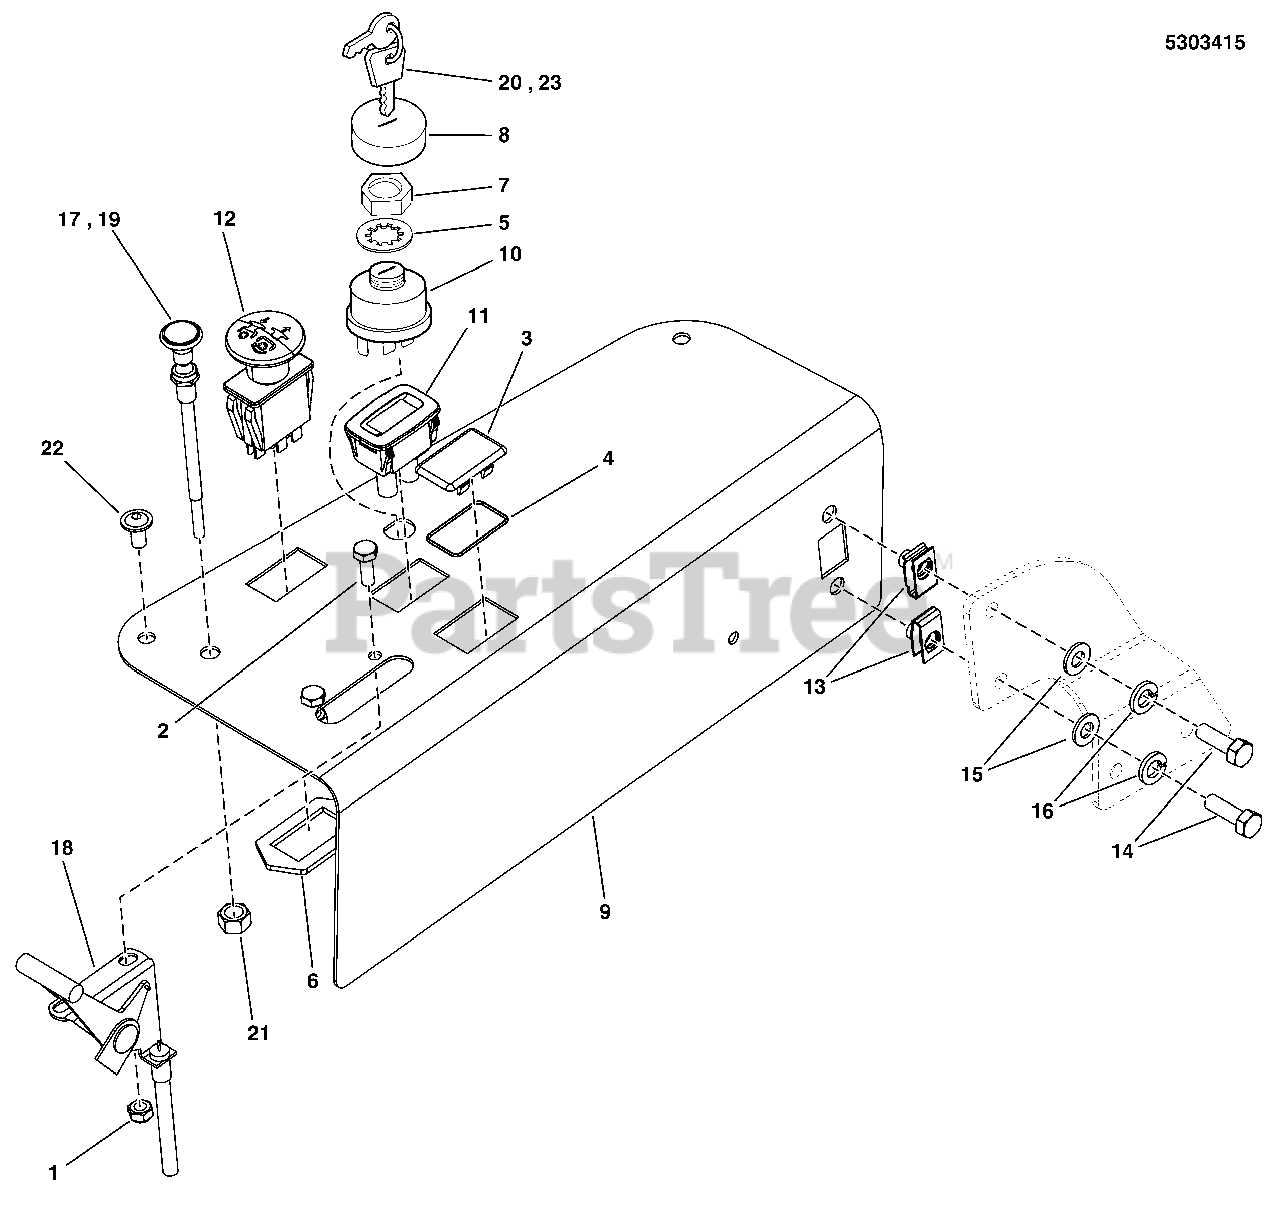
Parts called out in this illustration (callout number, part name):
1	NUT, Hex, Nylon Lock, 1/4-20
2	CAPSCREW, Hex Head, 1/4-20 x 3/4 (stiffener to top of cover)
3	PLUG, Hole, Electric Lift (Hydro models only)
4	O-RING, 7/8" ID X 1/16" W
5	LOCKWASHER, Internal Tooth, 5/8 Thin
6	RING, SWITCH RETAINER, PTO
7	NUT, Hex Flange, 5/8-32 IGN SW DIE CAST
8	COVER, Ignition Switch
9	PLATE, CONTROL PANEL, S550 - BLK
10	SWITCH ASSEMBLY, Ignition Indak No Keys/Hdwr
11	HOUR METER, 2 CHANNEL
12	SWITCH, PTO, Push/Pull
13	CLIP, BODY , 5/16-18 FOR 7 GA.
14	CAPSCREW, Hex Head, 5/16-18 x 1 1/4
15	WASHER, Flat, 5/16
16	WASHER, Flat
17	CABLE, Choke
18	CABLE, Throttle Control, 40"
19	CABLE, CHOKE CONTROL, 51 (Z)
20	KEYS, Ignition
21	NUT, 3/8-24 HEX JAM (SV)
22	SCREW, ALLEN HEAD 1/4-20 X .500 ZINC PHOS
23	KEYS, Ignition
